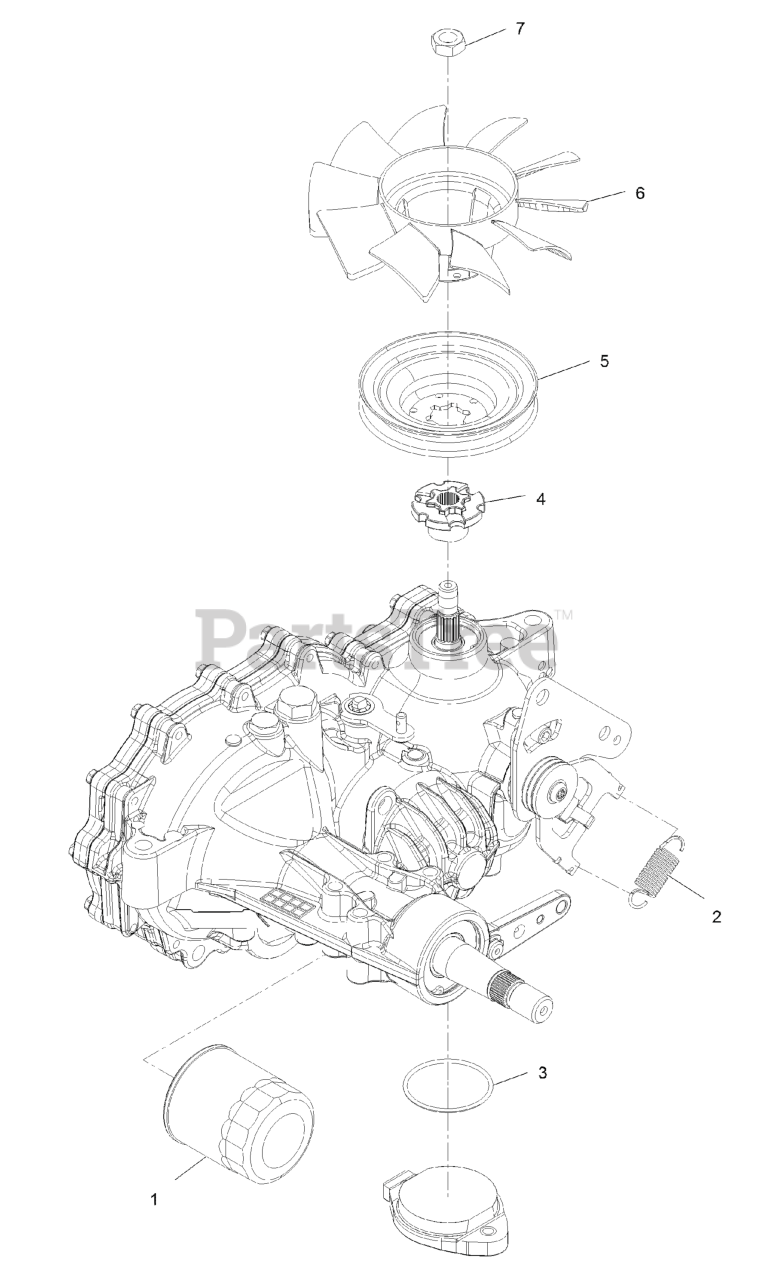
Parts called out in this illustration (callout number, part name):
1	ELEMENT-OIL FILTER, HYD
2	SPRING-EXTENSION
3	O RING-SEAL
4	HUB-PULLEY
6	FAN-7.0 INCH (10 BLADE)
